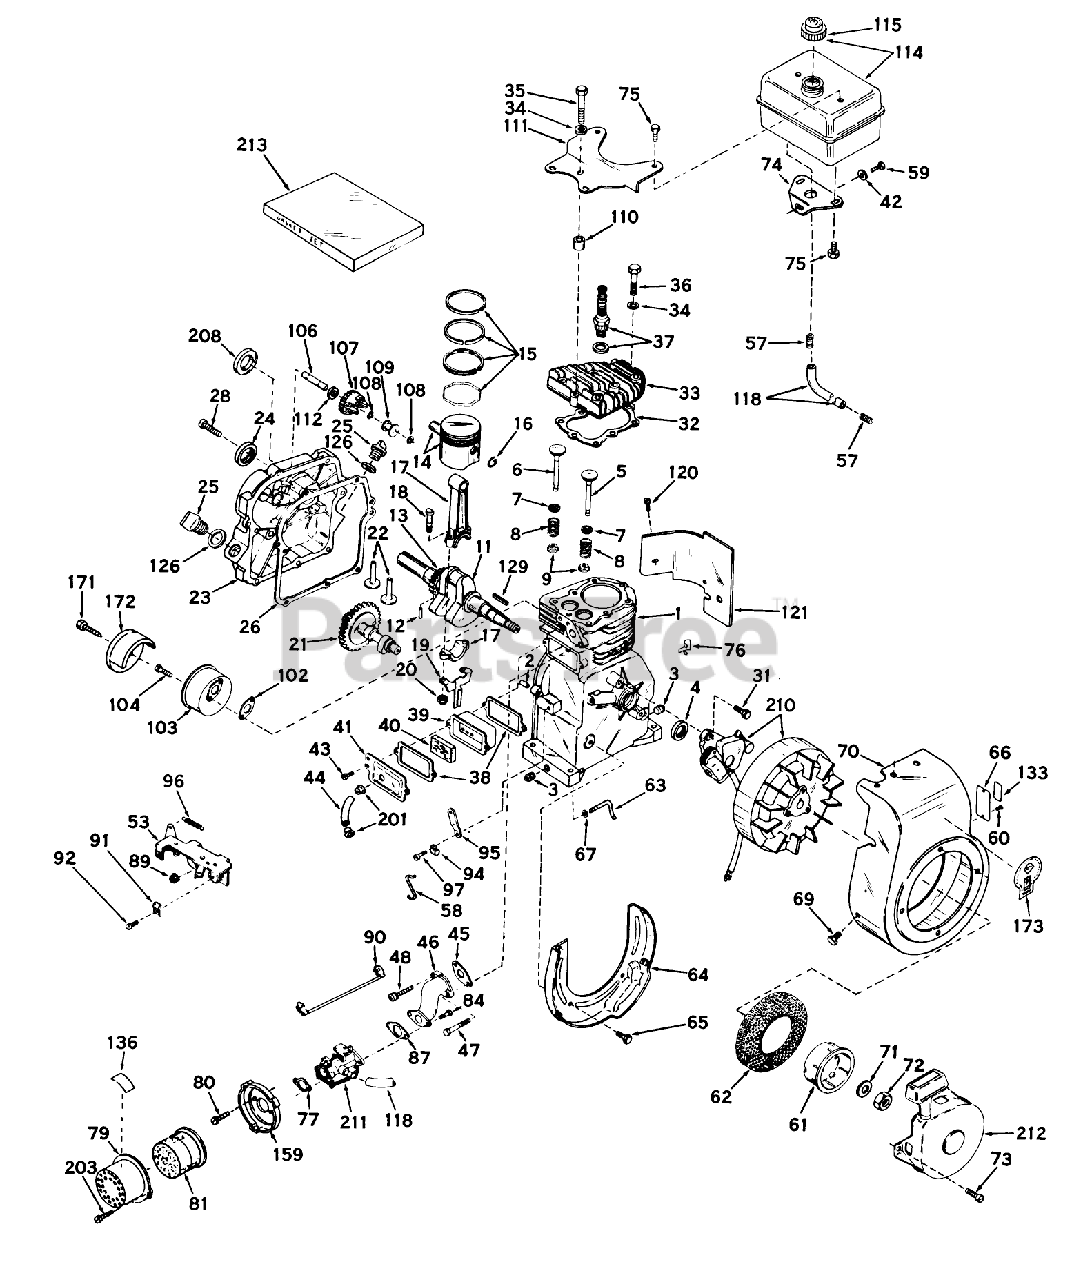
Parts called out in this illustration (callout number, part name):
1	Cylinder Assy.(Incl. Nos.2, 3 4)
2	Pin-Dowel
3	Plug-Drain, Oil (SQH 1/4-18)
4	OIL SEAL
5	Valve, Intake (Incl. Ref. #38, 39 40) (Std.)
5	Valve, Intake(1/32"overs.)(Incl. Ref. 8, 9 10)
6	Valve, Exhaust (Standard)(Incl. Ref. 8, 9 10)
6	Valve, Exhaust (1/32" Overs.(Incl. Ref. 8, 9 10)
7	Cap-Upper Valve Spring
8	Spring-Valve
9	Cap-Valve, Spring
11	Crankshaft Assy. (Incl. Nos. 12 13)
12	Pin, Groove
13	Gear, Crankshaft
14	Piston Pin Assy. (Standard) (Incl. 2 of No. 16)
14	Piston Pin Assy. (.010 Oversize) (Incl. 2 of No. 16)
14	Piston Pin Assy. (.020 Over size)(Incl. 2 of No. 16)
15	Ring Set, Piston (Std.)
15	Ring Set, Piston (.010 o.s.)
15	Ring Set, Piston (.020 o.s.)
16	Ring-Retaining, Piston Pin
17	Rod Assy., Connecting (Incl. Ref. #17)
18	Bolt, Connecting
19	53020/22 GIL.HYDRO
20	LOCKNUT
21	Camshaft, BCR, Extended
22	Lifter-Valve
23	Cover, Cylinder (Incl. Nos. 24, 25, 26, 106, 126 208)
24	Seal, Oil
25	Plug-Fill, Oil
26	Gasket-Cylinder Cover
28	Screw
31	Screw
32	Gasket-Cylinder Head
33	CYLINDER HEAD
34	Washer
35	Screw Hex Hd. Cap
36	Screw
37	SPARK PLUG
38	Gasket-Breather
39	Body-Breather
40	Element, Breather
41	Gasket-Gear Case
42	Washer
43	Screw
44	Breather Tube
45	Gasket-Intake
46	Pipe, Intake
47	Screw
48	Screw
53	Bracket Control
57	Spring, Coil
58	Jet-Main
59	Screw (1/4-20x19/32)
60	DRIVE STUD
61	Starter Cup
62	Screen, Air
63	Rod-Governor
64	Baffle, Blower Hsg.
65	Screw (1/4-20x19/32)
66	IDENTIFICATION PLATE
67	Washer-Flat
69	Screw
70	Housing,Blower
71	Washer
72	Hex Nut
73	Screw
74	Bracket, Fuel Tank Lower
75	Screw (1/4-15x7/8)
76	Clip-Wire
77	Gasket
79	Body
80	Screw (10-32 x 1/2)
81	AIRCLEANER
87	Gasket
89	Nut and Lock Washer (1/4-28)
90	Wire, Ground
91	Conduit
92	Screw (10-32 x 3/8)
94	Clamp-Lever, Governor
95	Lever-Governor
96	Spring-Extension
97	Screw
102	Gasket Exhaust
103	Muffler
104	Screw
106	Shaft-Governor
107	Governor Gear ASM
108	Ring-Retaining
109	Spool-Governor
110	pacer
111	Bracket, Fuel tank
112	Washer-Flat
114	53023/VAR.10/16HP O
115	Cap-Fuel
118	Line-Fuel
120	Screw
121	Extension-Blower
126	Gasket
129	Key Flywheel
133	Decal, Instruction
136	DECAL, AIRCLEANER
159	BRACKET, AIRCLEANER
171	Screw, Muffler
172	Cover-Muffler
173	Decal, Name H.P.
201	GROMMET
203	Screw
208	Seal, Oil
210	Magneto
211	Carburetor
212	Starter, Rewind
213	Gasket Set
